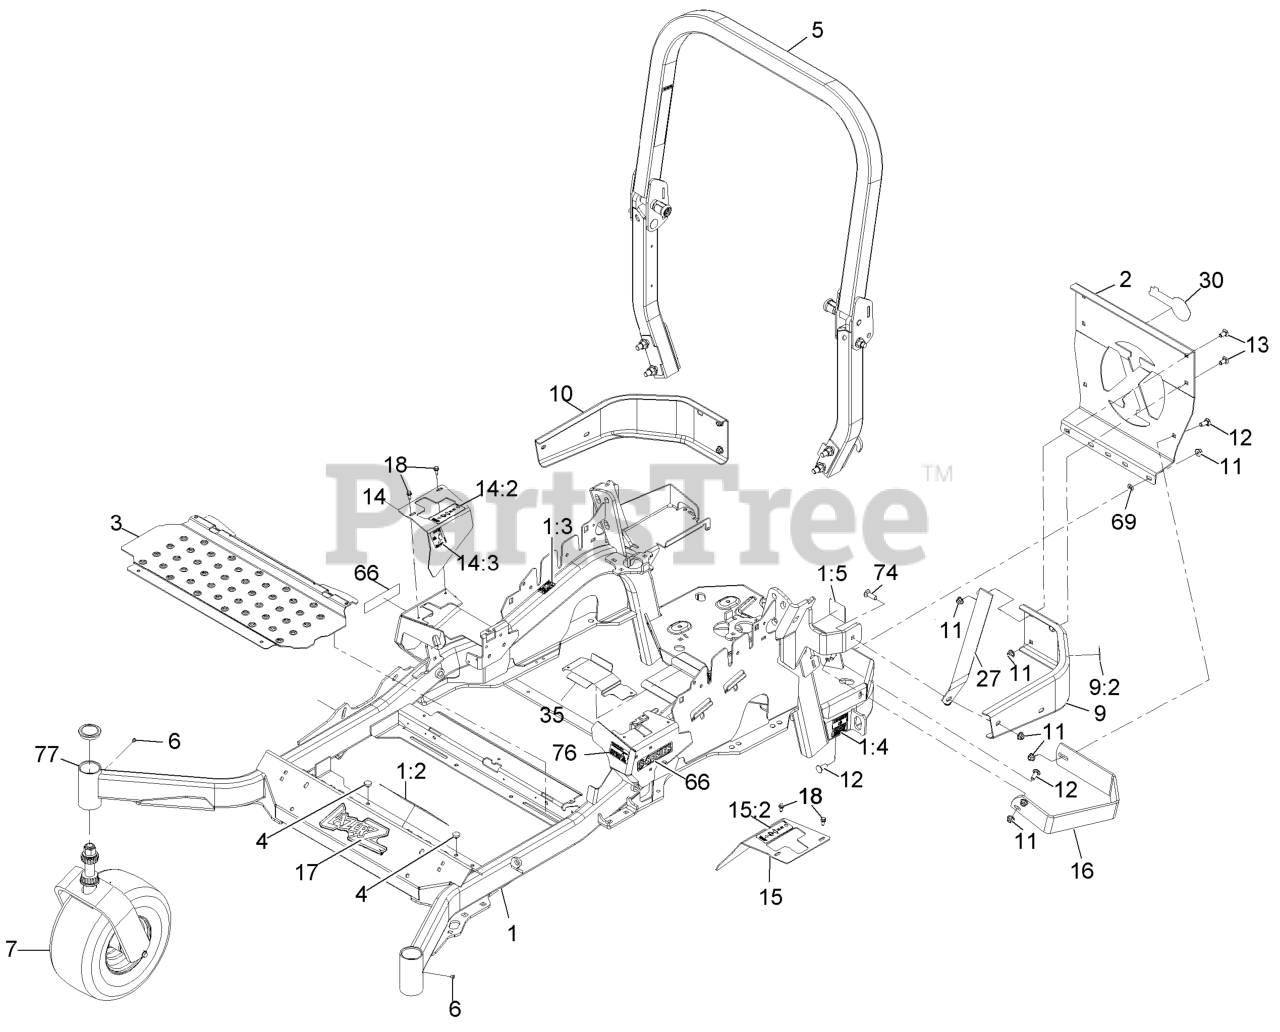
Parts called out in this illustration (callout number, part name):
1	MAINFRAME ASM
1:2	DECAL-SLOPE
1:3	DECAL-CAUTION
1:4	DECAL-BELT DRIVE
1:5	DECAL-SPARK ARRESTER
2	PLATE,REAR GUARD
5	ROPS ASM
7	Front Caster And Fork Asm
9	LH BUMPER ASM
9:2	DECAL-CAUTION
10	BUMPER-RH
11	NUT-HF, NI
12	SCREW-CARR
13	SCREW-CARR
14	RH MOTION CONTROL COVER ASM
14:2	DECAL-MOTION CONTROL
14:3	DECAL-PARK BRAKE
15	LH MOTION CONTROL COVER ASM
15:2	DECAL-MOTION CONTROL
16	GUARD-MUFFLER
17	DECAL,LAZER MODEL
18	SCREW-HWH
35	GUARD-BELT
66	DECAL-E-SERIES
69	NUT-PUSH
74	BOLT-CARR
76	DECAL-FUEL FILL
77	CUP-BEARING
